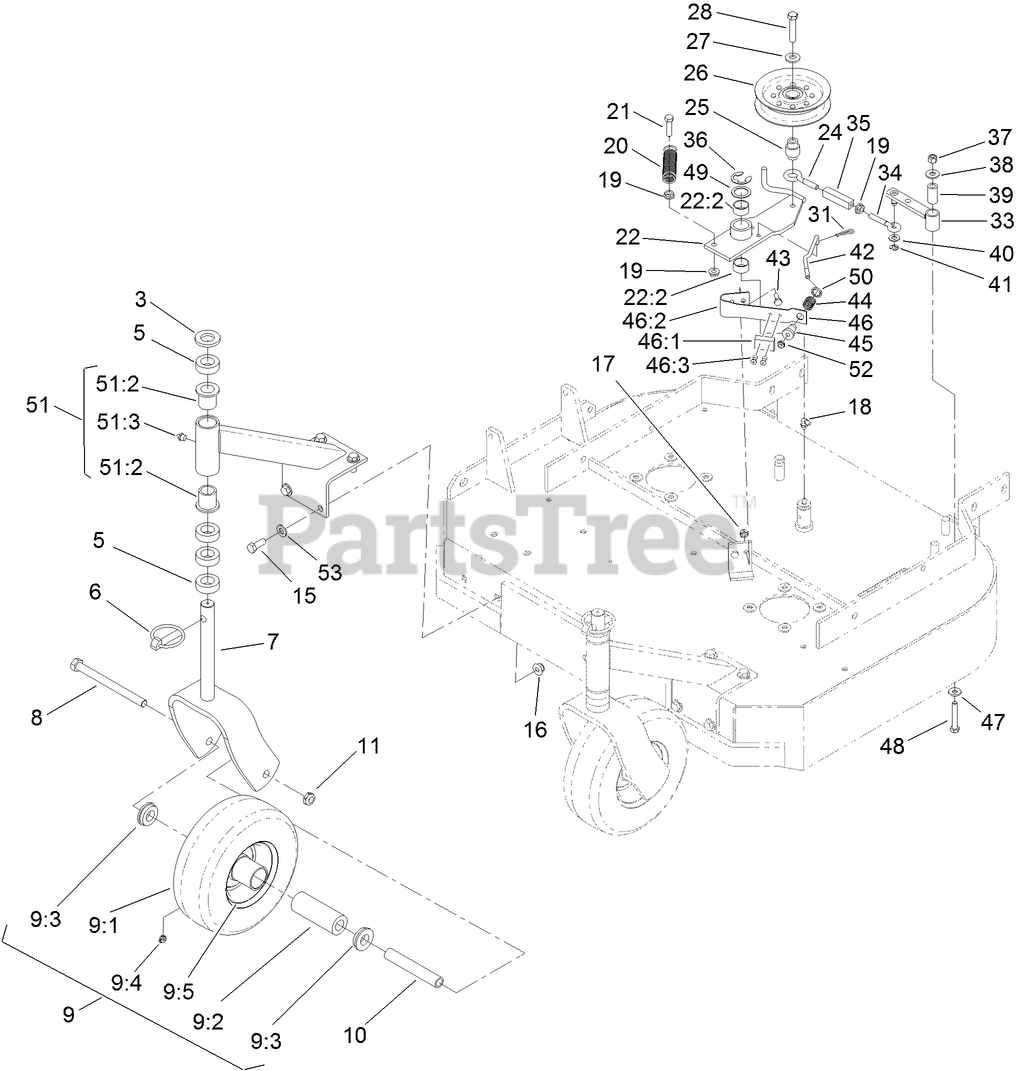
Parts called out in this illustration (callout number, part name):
3	WASHER-FLAT
5	SPACER-CASTER
7	FORK-CASTER
8	SCREW-HH
9	WHEEL AND TIRE ASM
9:1	TIRE
9:2	BEARING
9:3	BUSHING
9:4	FITTING-GREASE
9:5	WHEEL
10	SPACER
11	NUT-HEX
15	SCREW-HH
16	NUT-HF, NI
17	NUT-LOCK, NI
18	FITTING-GREASE, 90 DEG
19	NUT-HF
20	SPRING-EXTENSION
21	SCREW-HH, SPECIAL
22	IDLER ARM ASM
22:2	SLEEVE-BEARING
24	EYEBOLT-THREAD, LH
25	BUSHING-ENGAGEMENT
27	WASHER-BELLEVILLE
28	SCREW-HH
31	PIN-COTTER
33	ARM-ASSIST, 32/36
34	EYEBOLT-THREAD, RH
35	BODY-TURNBUCKLE
36	RING-RETAINING, EXT
37	NUT-LOCK, NI
38	WASHER-FLAT
39	TUBE-PIVOT
40	WASHER-PLAIN
41	RING-RETAINING, EXT
42	ROD-BRAKE
43	SCREW-HH
44	SPRING-COMPRESSION
45	SPACER-FLANGED
46	PAD AND SPRING ASM
46:1	PAD-BRAKE
46:2	SPRING
46:3	RIVET-POP
47	WASHER-SPRING
48	SCREW-HH
49	WASHER-SPINDLE
50	RING-PUSH ON
51	SUPPORT ASM
51:2	BEARING-FLANGED
51:3	FITTING-GREASE
52	NUT-LOCK, NI
53	WASHER-FLAT
